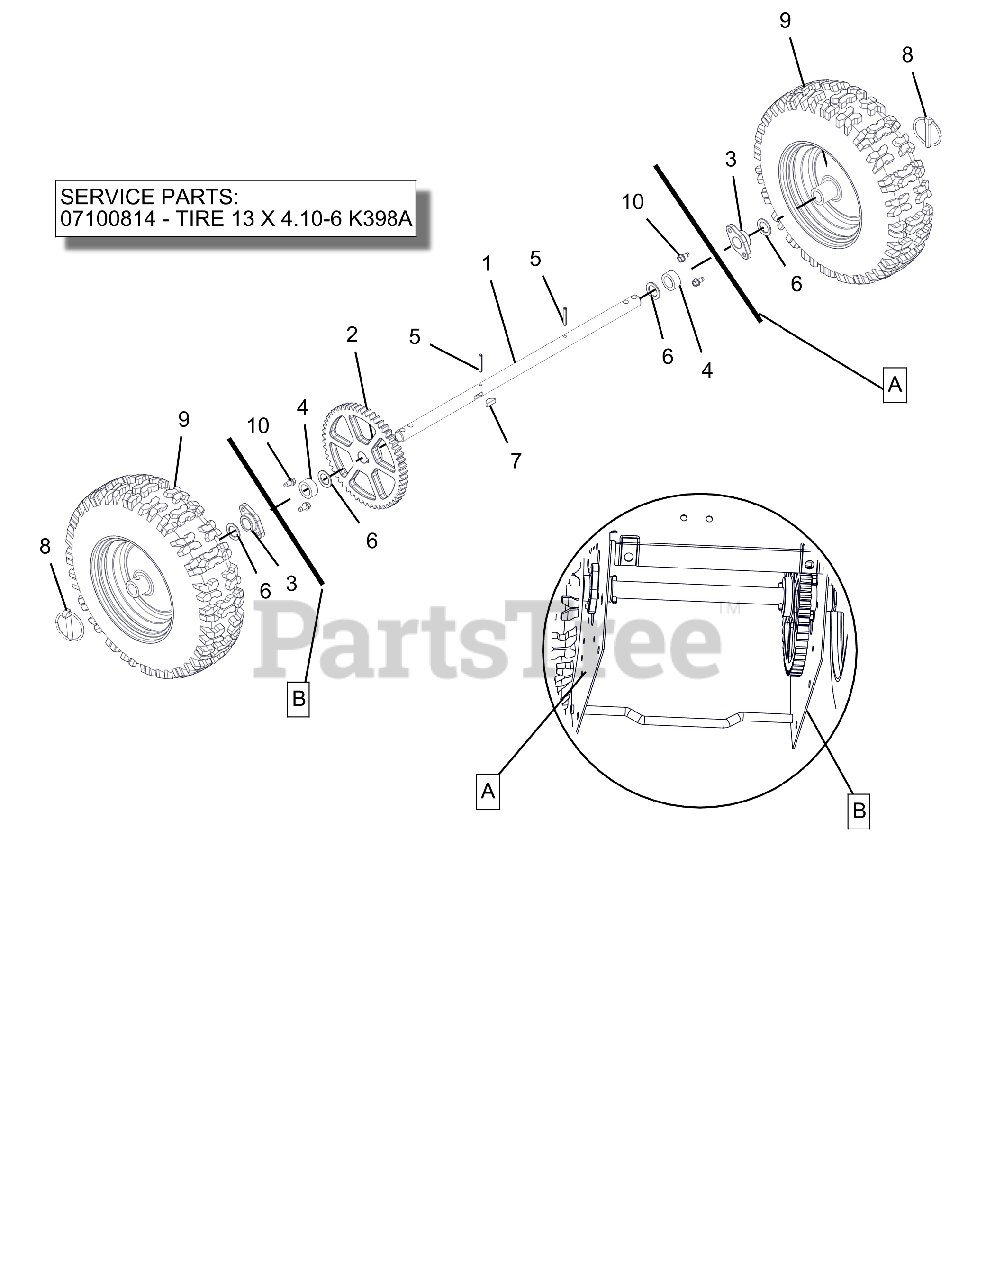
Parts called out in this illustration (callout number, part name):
1	SHAFT, AXLE
2	SPUR GEAR, 54T .75ID X 6.75PD
3	BSHG .75X1.125X.65
4	BSHG-SLV .766 X 1.125 X .500
5	PIN-ROLL .188X1.25
6	WSHR-FL-STL.754X1.125X.062YWZC
7	KEY-WDRF .25X.750X.313 SAE91
8	PIN-LOK .31X1.75
9	TIRE/WHEEL, 13X4.10-6 K398A
9	TIRE, 13" K398A
10	SCR-TAP .25-20X.50 HWH TR YWZ
